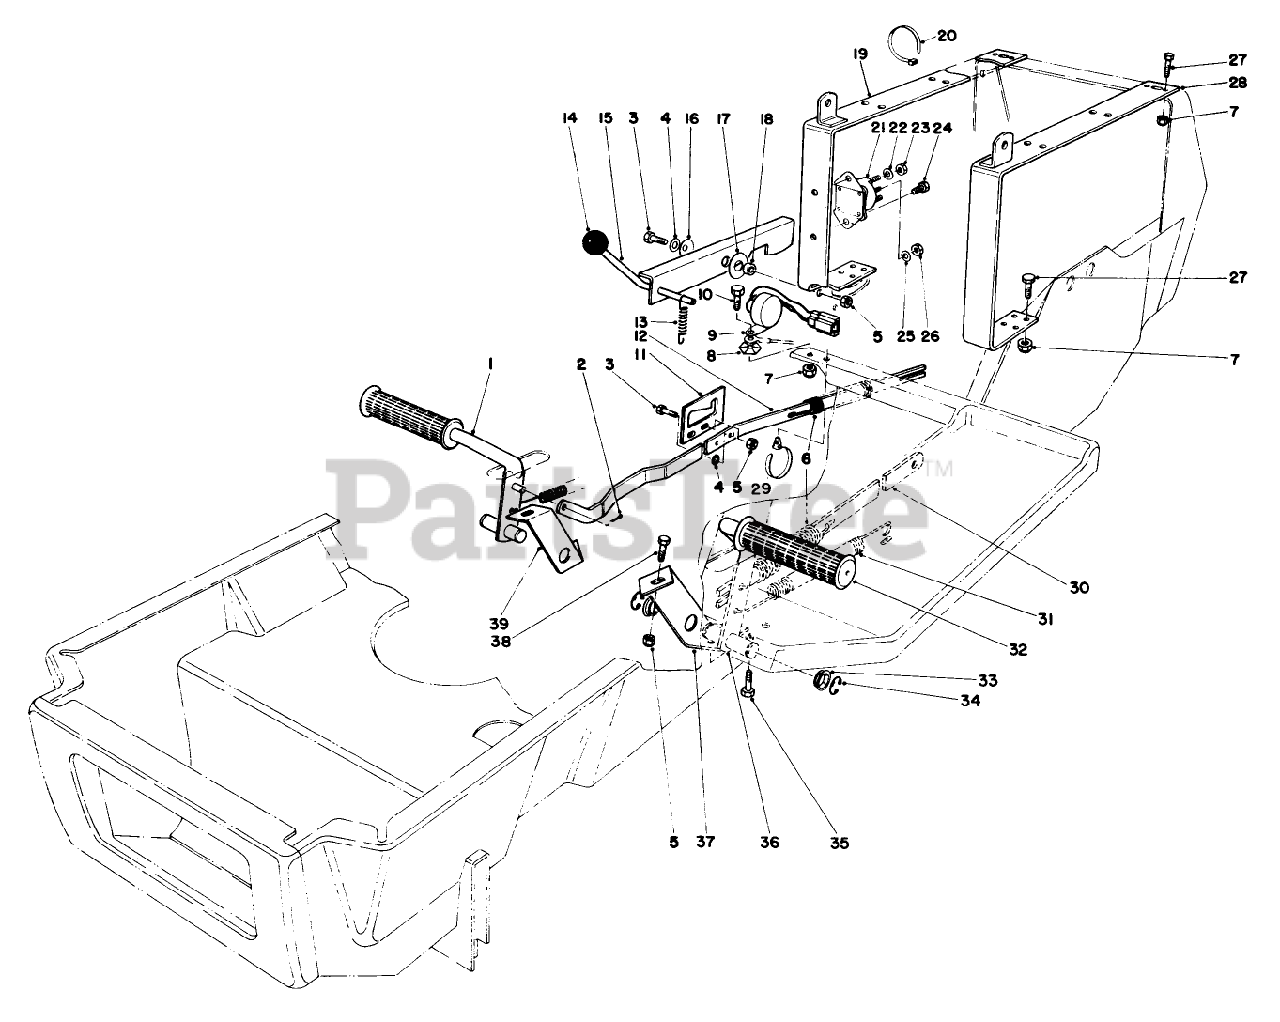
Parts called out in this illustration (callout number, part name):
2	PIN-COTTER
3	SCREW-HH
4	WASHER-PLAIN
5	NUT-LOCK, CONE
10	Bolt
14	Knob
16	Belleville Washer
17	WASHER-PLASTIC
20	TIE-CABLE
21	Solenoid
22	Lockwasher
23	NUT-JAM, BRASS
24	SCREW-HWH
25	NUT-HEX
26	WASHER-LOCK
27	SCREW-HH
29	10 Pushmount Tie
31	SPRING-EXTENSION
34	E-RING
35	SCREW-THD ROLL, HWH
36	CLUTCH PEDAL WA *BO
38	SCREW-HH
